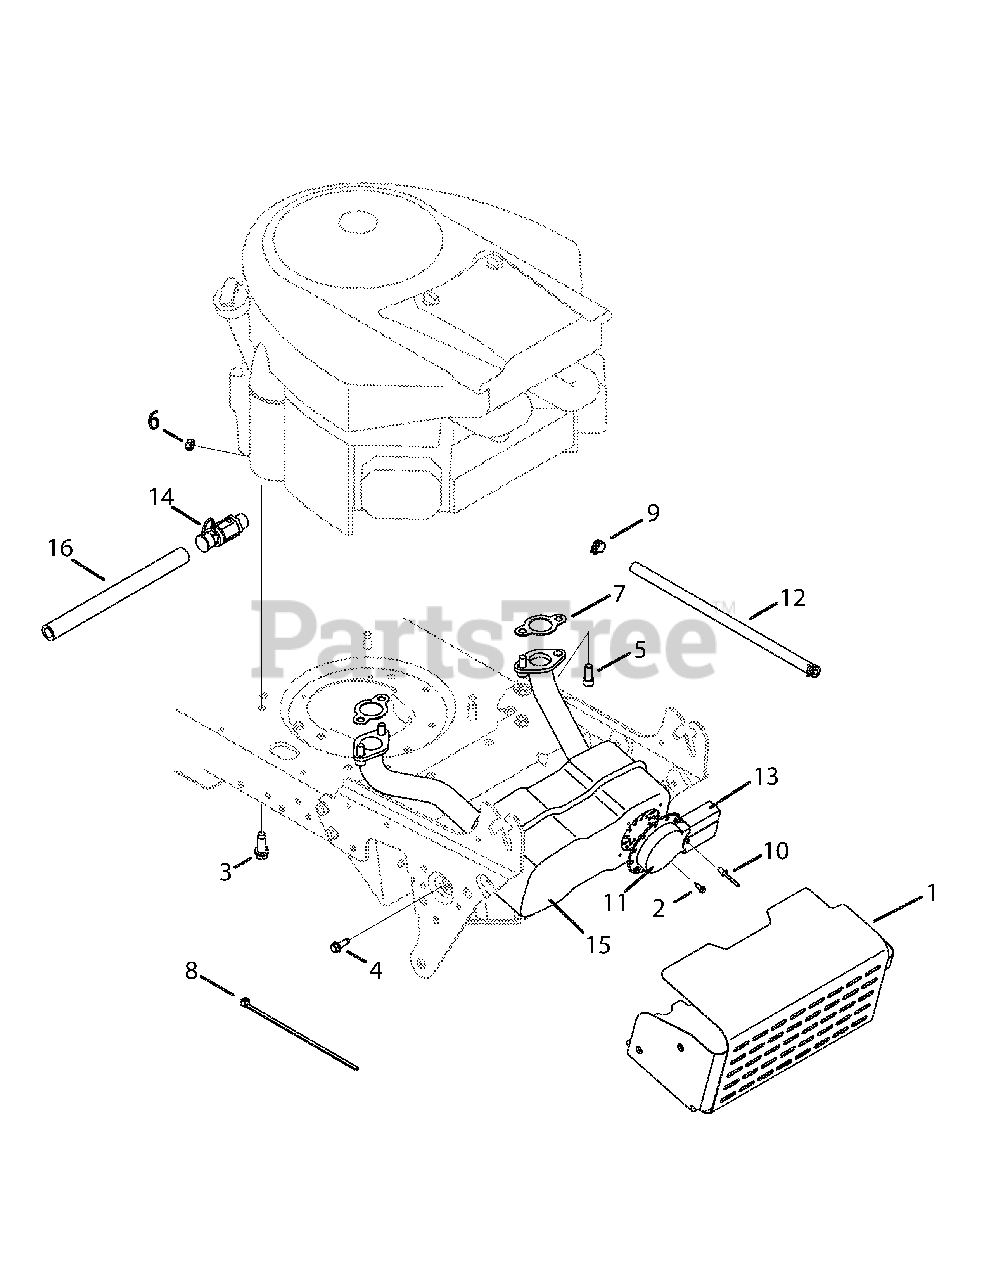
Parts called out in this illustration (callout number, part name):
2	Screw, #8-18, 0.500
3	Screw, Hex, 3/8-16 x 1.00
4	Screw, Hex, 1/4-20, 0.750
5	Screw, 5/16-18, 0.75
6	Sems Nut, 1/4-20
7	Exhaust Gasket, B&S Twin
8	Cable, Tie, 3/16 x .05 x 7.4
9	Hose Clamp
10	Rivet, Pop, .188 x .325
11	Deflector, Muffler
12	Fuel Line, Low Permeation
13	Extension, Deflector
14	Drain, Oil
15	Muffler, Dual Inlet, B&S
16	Extension Hose, Oil Drain
